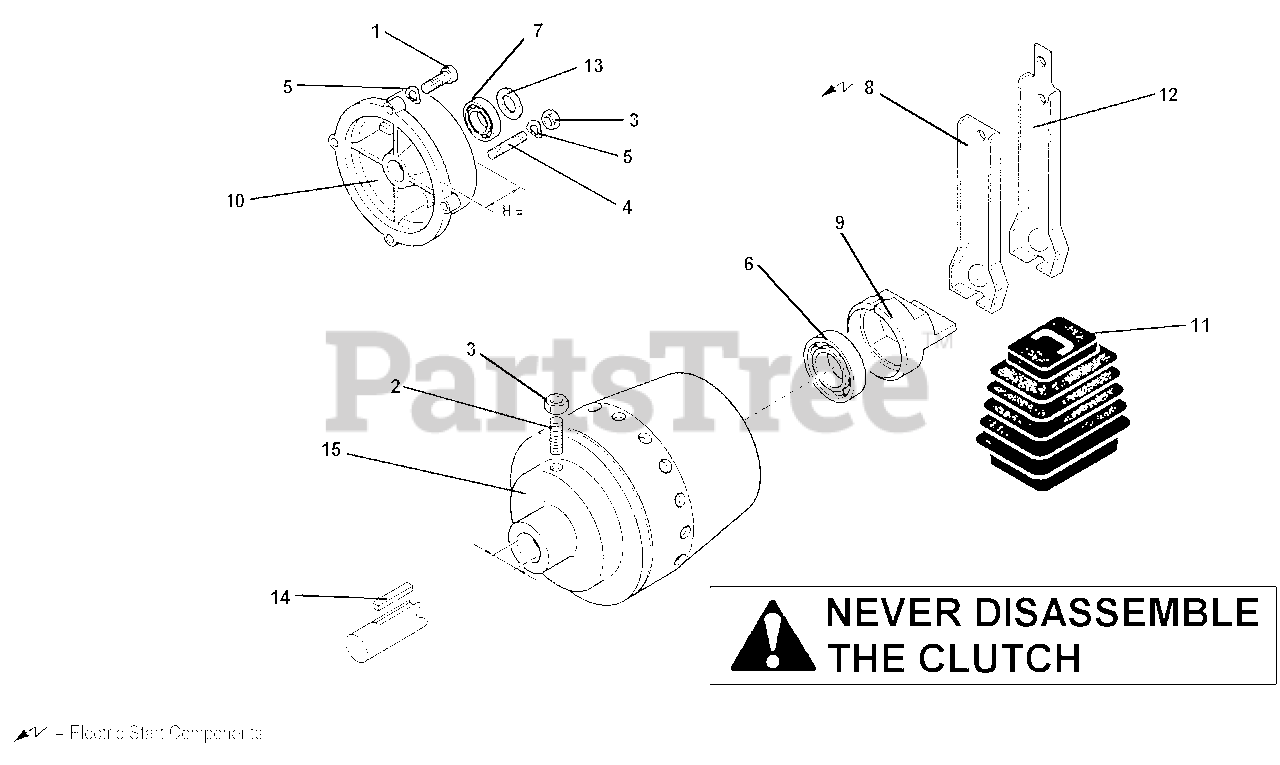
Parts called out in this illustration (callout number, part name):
1	SCREW 5/16X7/8
2	SCREW M8X30
4	STUD,M8X40X14X14
5	WASHER, WAVE
6	BEARING,M17X40X12
7	BEARING,M20X47X14
8	CLUTCH LEVER, ELECTRIC START
9	CONE PUSHER
11	BOOT, ELECTRIC START
12	CLUTCH LEVER, RECOIL START
15	CLUTCH, 5.5/6.5 INTEK & GX160
